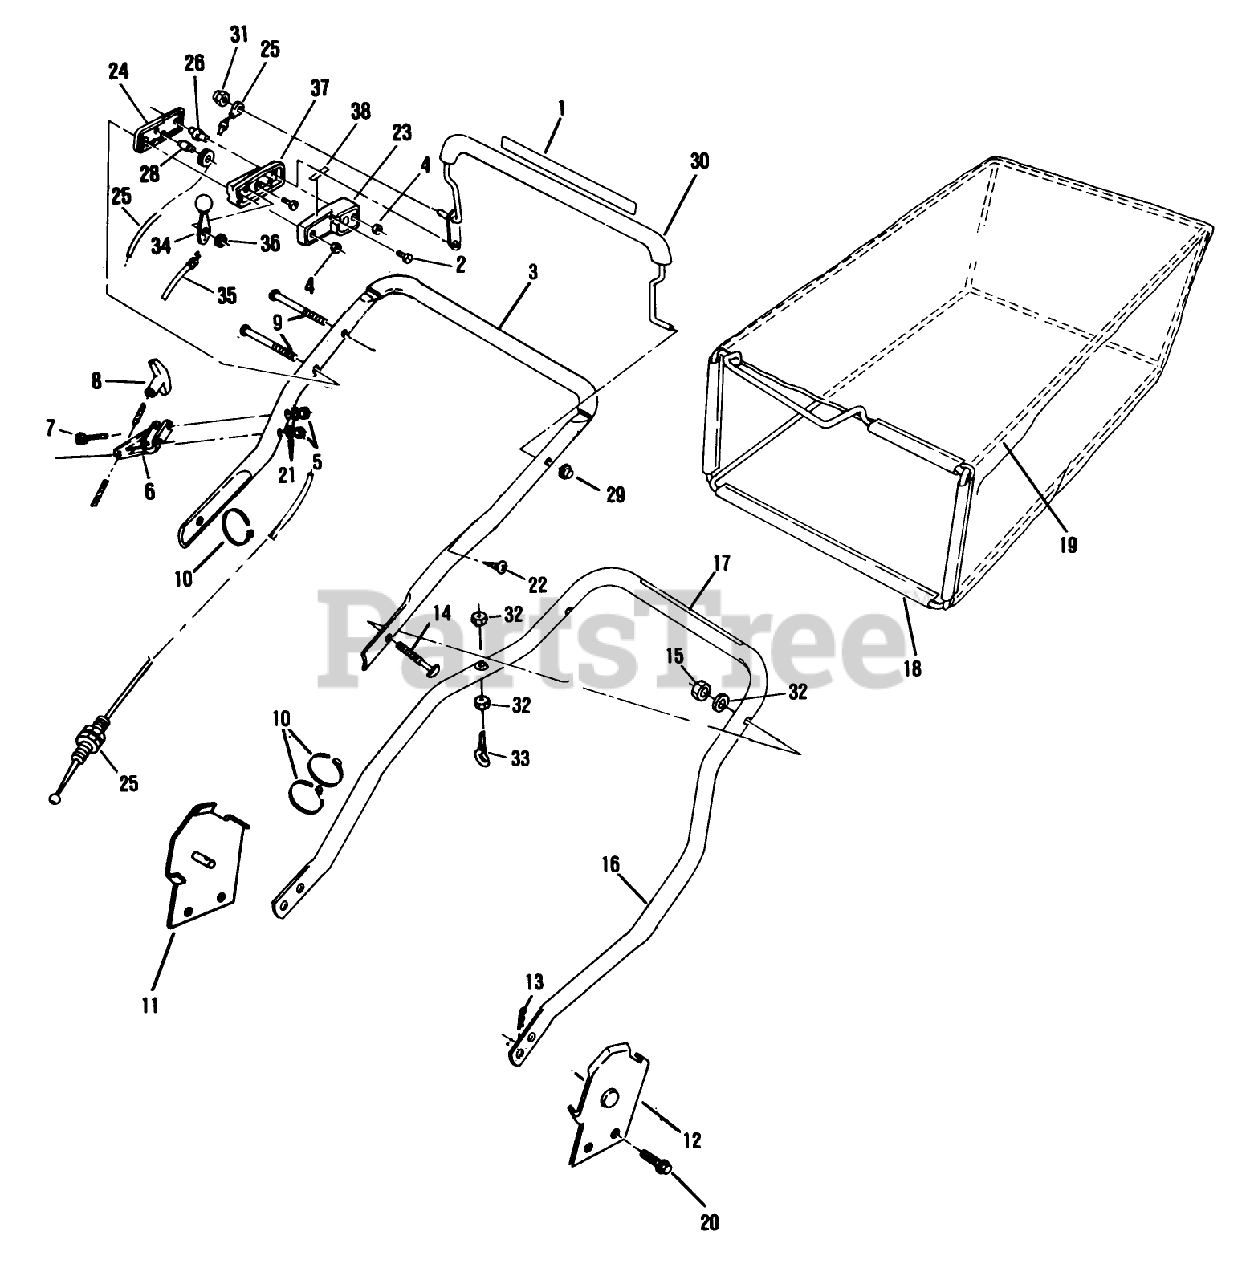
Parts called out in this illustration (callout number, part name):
2	SCREW
3	HANDLE-TOP *G
4	NUT C/LOCK E
5	LOCKNUT E
8	HANDLE START UM&D
9	SCREW
13	HAIR PIN
15	NUT-LOCK F
21	WASHER
22	SCREW LAWRENCE
25	CONTROL CABLE WES
26	COLUMN
27	PULLEY PL
28	PIN SKF
31	NUT ACORN
32	WASHER-CURVED
33	EYE BOLT WAS MFG
34	LEVER&KNOB AY WES
35	CABLE THROT WES
36	WASHER-SPRING
